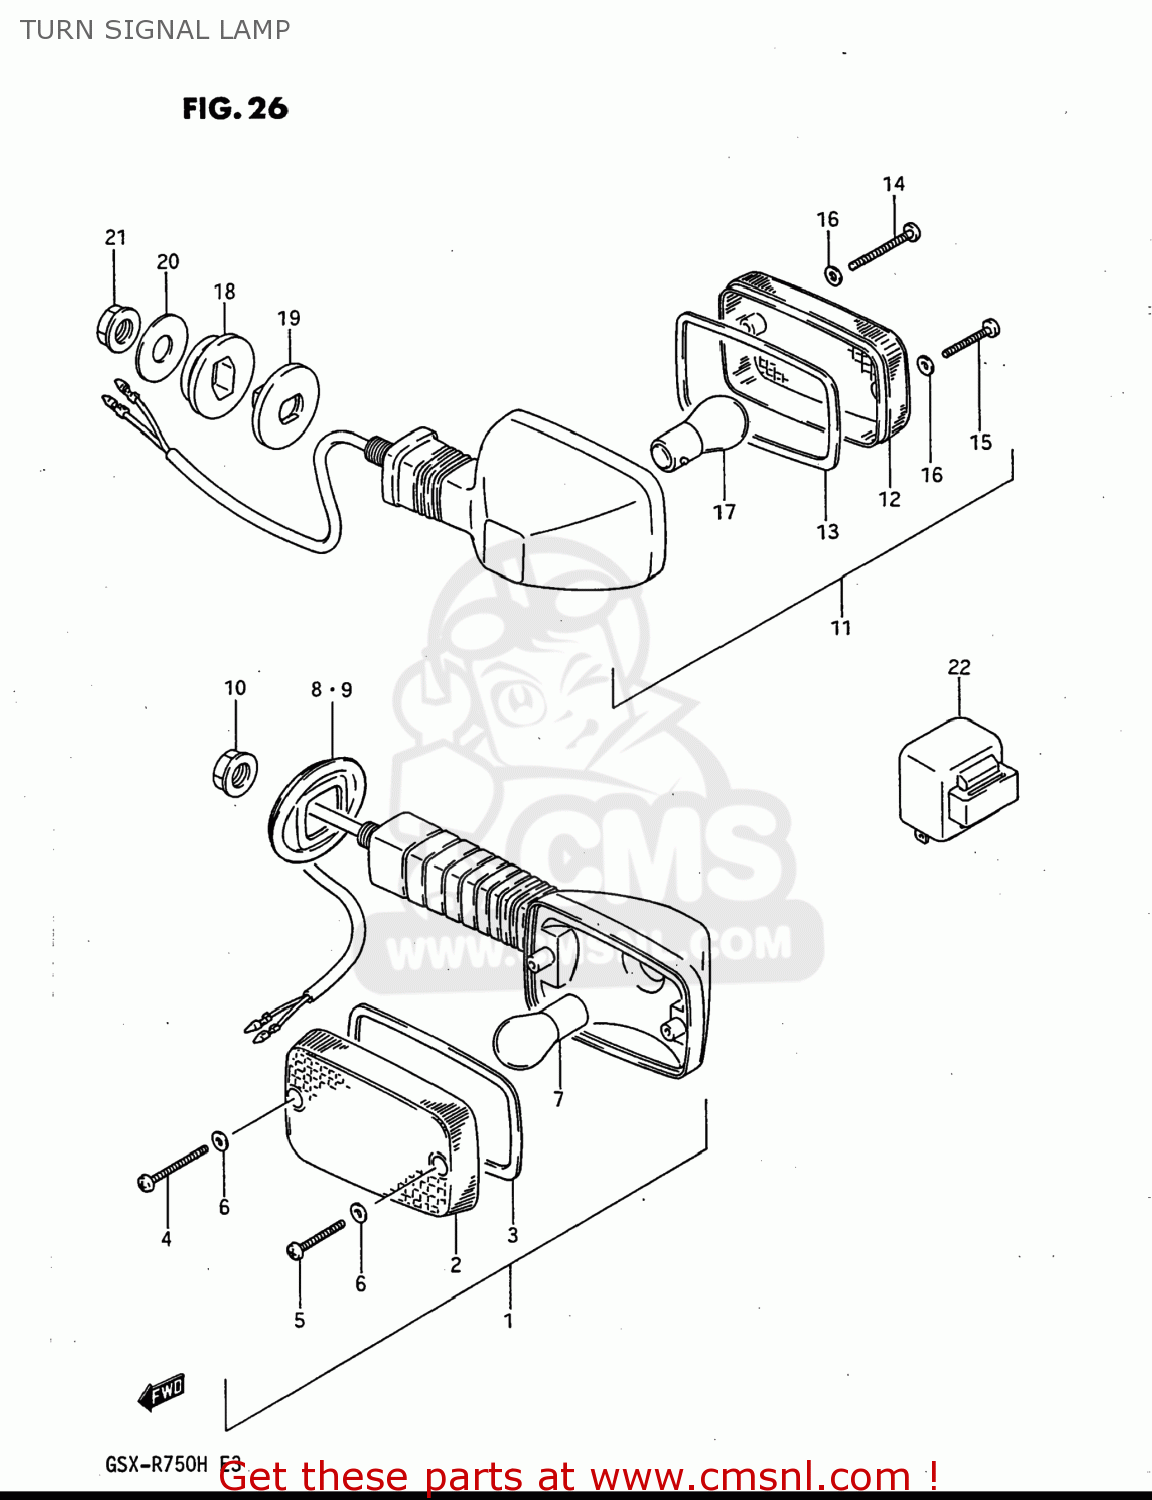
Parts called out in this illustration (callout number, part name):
1	LAMP ASSEMBLY,FRONT TURN SIGNAL
2	LENS,FR
3	GASKET (NAS)
4	SCREW,TURN SIG LENS FITTING
5	SCREW
6	GASKET (NAS)
7	BULB(12V23W,STANLEY,A4577A)
8	GROMMET,TURNSIGNAL LAMP,R
9	GROMMET,TURNSIGNAL LAMP,L
10	NUT
11	LAMP ASSEMBLY,REAR TURN SIGNAL
12	LENS,RR
13	GASKET (NAS)
14	SCREW,TURN SIG LENS FITTING
15	SCREW
16	GASKET (NAS)
17	BULB(12V23W,STANLEY,A4577A)
18	CUSHION
19	SPACER
20	WASHER (10.2X27X1.6)
21	NUT
22	RELAY ASSEMBLY,TURN SIGNAL
